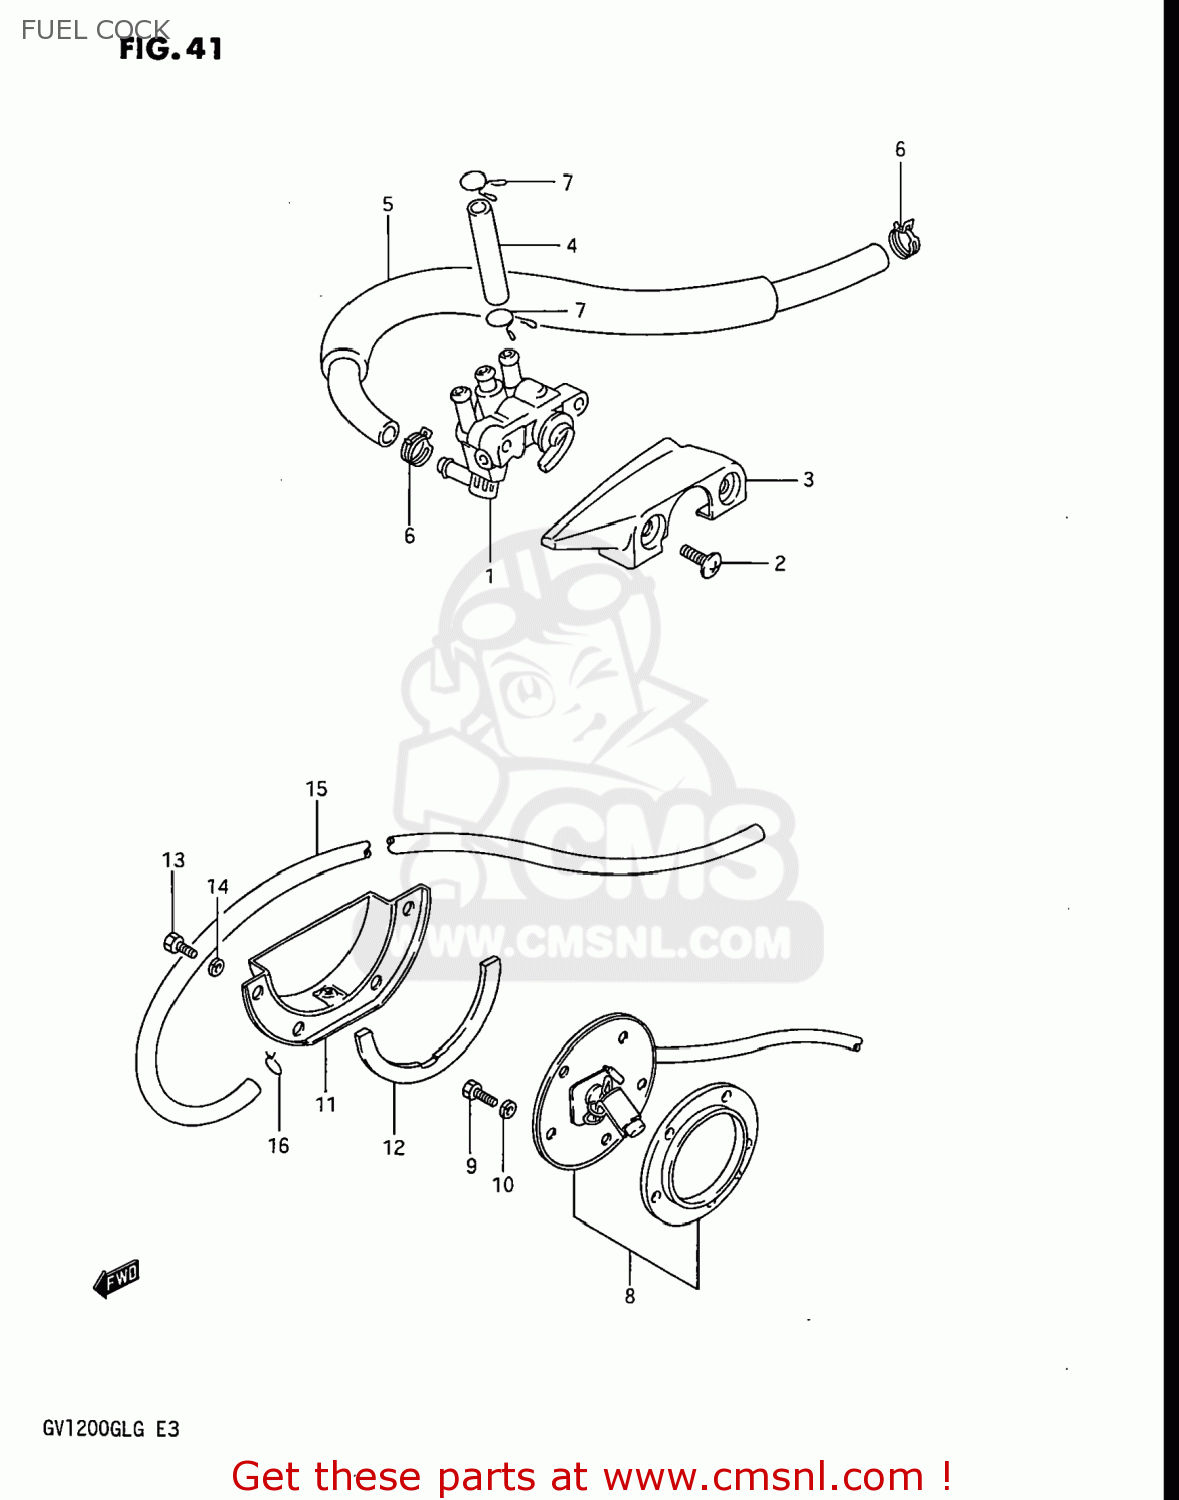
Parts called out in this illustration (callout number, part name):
1	COCK ASSEMBLY,FUEL
2	SCREW
3	COVER.FUEL COCK
4	HOSE
5	HOSE
6	CLAMP
7	CLIP
8	GAUGE ASSEMBLY,FUEL LEVEL
9	BOLT
10	LOCK WASHER
11	PLATE,FUEL DRAIN
12	GASKET (NAS)
13	SCREW
14	LOCK WASHER
15	HOSE,FUEL
16	CLIP
